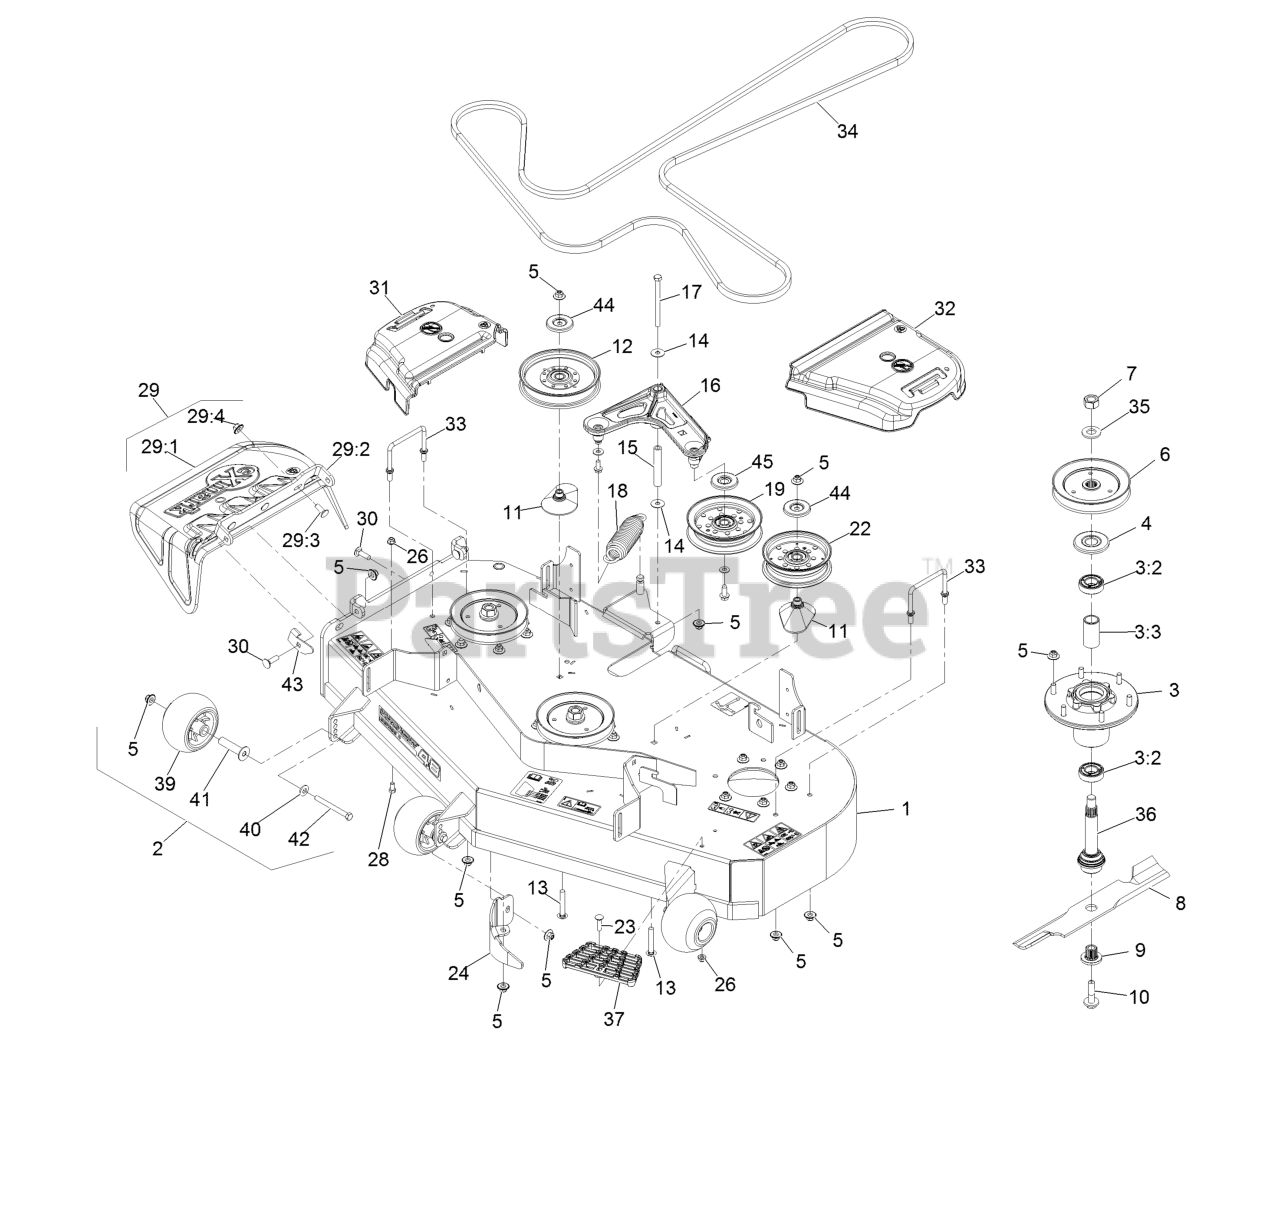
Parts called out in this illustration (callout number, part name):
1	ASM-Deck W/Decals 484
2	Kit, Anti-Scalp Roller
3	ASM-Cutter Hsg With Bearings
3:2	Bearing-Ball
3:3	Spacer-Bearing
4	Guard,Bearing Top .989
5	Nut-Nyloc 3/8-16 Flg
6	Sheave,Blade Drive 5.90
7	Nut-Hex
8	Blade-Extreme 2, 16.25"
8	Blade-Notched
8	Blade, Mulching
8	Blade, Low Lift
8	Blade, Solid
9	Bushing, Splined
10	Screw-Sems 1/2-20 X 2.19
11	Spacer-Pulley
12	Idler-Pulley, Flat 6.00X1.00
13	Bolt-Carriage 3/8-16 X 2 1/2
15	Bushing
16	Idler Arm ASM
17	Screw-HH 3/8-16 X 4 3/4
18	Spring-Extension
19	Idler-Pulley, Flat
22	Idler-Pulley, Flat 5.00X1.31
23	Bolt-Carriage 5/16-18 X 1 1/4
24	Baffle-Dogleg,Lzs Lzx Vt48
26	Nut-Nyloc 5/16-18 Flg
28	Screw-HH 5/16-18 X 5/8
29	ASM,Discharge Chute
29:1	Chute, Discharge
29:2	Bracket,Discharge Chute
29:3	Bolt-Carriage 3/8-16 X 1
29:4	Nut-Nyloc 3/8-16 Flg
30	Bolt-Carriage 3/8-16 X 1 1/4
31	Cover-Belt, RH
32	Cover-Belt, LH
33	Wireform-Cover
34	Belt-V
35	Washer-Spring Disc 3/4
36	ASM-Spindle And Seal
37	Step-Deck
39	Roller-Anti-Scalp
40	Washer-Spring Disc 3/8
41	Axle, Roller
42	Screw-HH 3/8-16 X 3 3/4 GR 8
43	Stop-Discharge Chute
44	Shield-Dust
45	Shield-Guard, Dust
